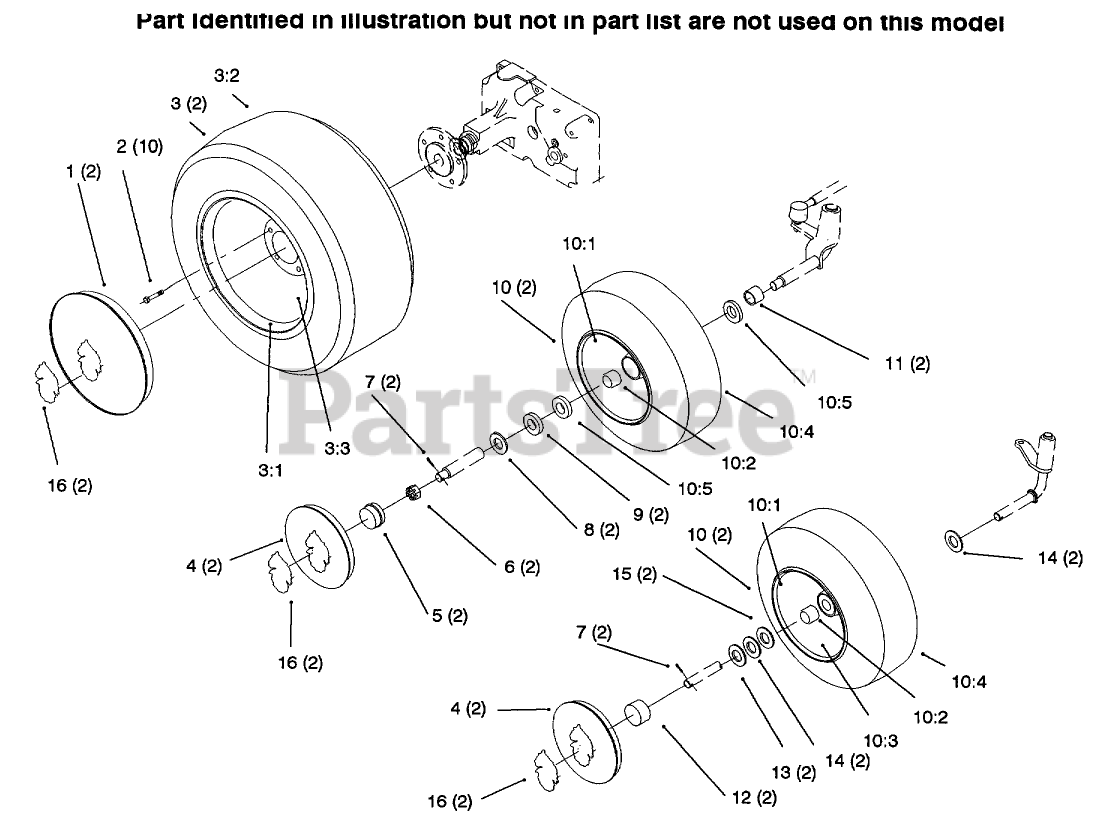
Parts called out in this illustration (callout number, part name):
2	BOLT-LUG
3	ASM-Wheel Tire
3:1	RIM ASM
3:3	VALVE
5	DUST CAP
6	NUT-HEX, SLOTTED
7	PIN-COTTER
8	WASHER
10:2	SEAL-OIL
10:3	VALVE
10:5	SEAL-OIL
11	SPACER
